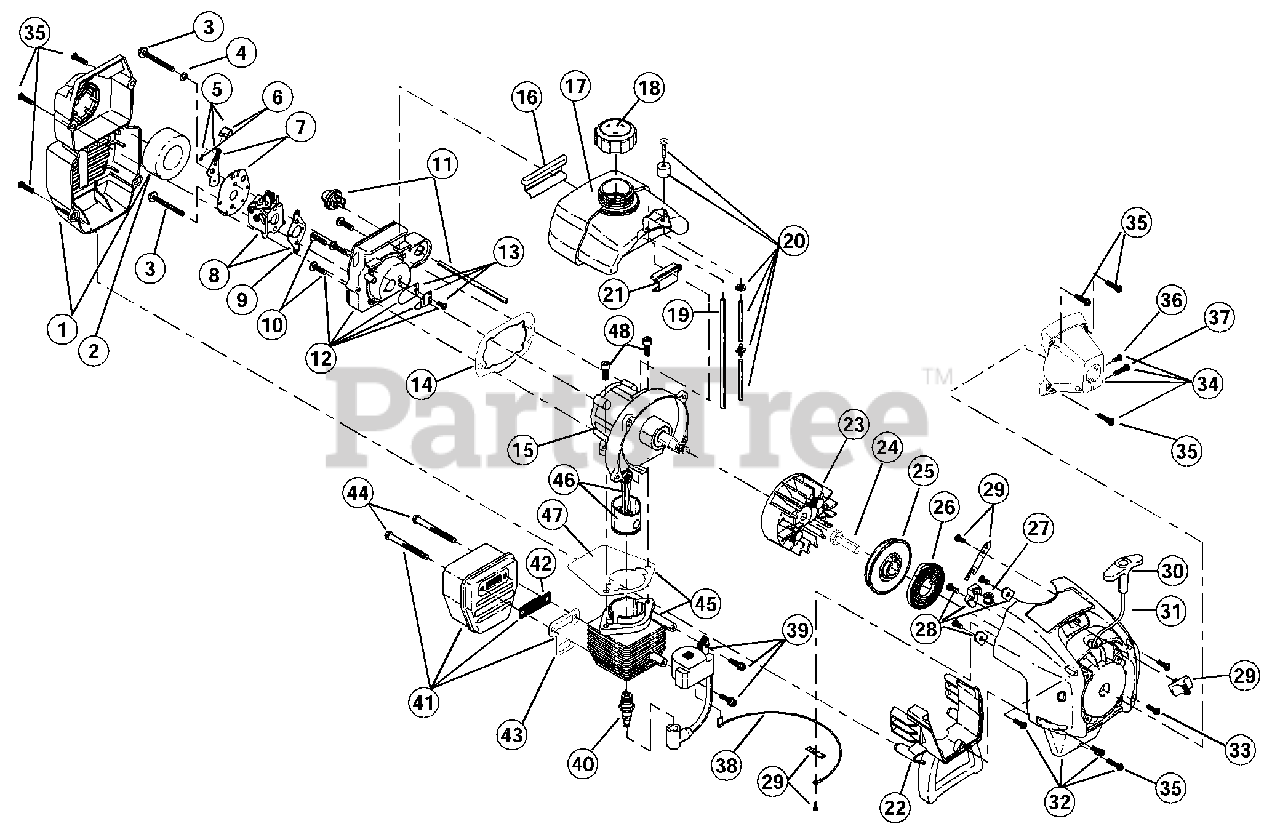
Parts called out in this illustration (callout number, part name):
1	Air Cleaner/Muffler Cover Assembly
2	Air Cleaner Filter
3	Carburetor Mounting Screw Assembly
4	Wavey Washer
5	Choke Lever Assembly
6	Choke Knob and Screw
7	Choke Lever and Plate
8	Carburetor Assembly
9	Carburetor Gasket
10	Carb Mount Screw
11	Primer and Hose Assembly
12	Carb Mount Assembly
13	Reed Assembly
14	Carburetor Mount Gasket
15	Crank Case Service Assembly
16	Rear Mounting Pad
17	Fuel Tank Assembly
18	Fuel Cap Assembly
19	Fuel Return Line
20	Fuel Line Assembly
21	Front Mounting Pad
22	Shroud Extension and Stand
23	Flywheel Assembly
25	Recoil Pulley Assembly
26	Recoil Spring
27	Rope Guide
28	Pulley Retainer Assembly
29	Switch Assembly
30	Pull Handle
32	Starter Housing Assembly
33	Housing Screw
34	Clutch Cover Assembly
35	Cover Screw
36	Anti-Rotation Screw
37	Clamping Screw
38	Wire Lead
39	Module Assembly
40	Spark Plug
41	Muffler Assembly
42	Spark Arrestor Screen
43	Exhaust Gasket
44	Muffler Mounting Bolt Assembly
45	Cylinder Assembly
46	Piston and Rod Assembly
47	Cylinder Gasket
48	Cylinder Bolt
